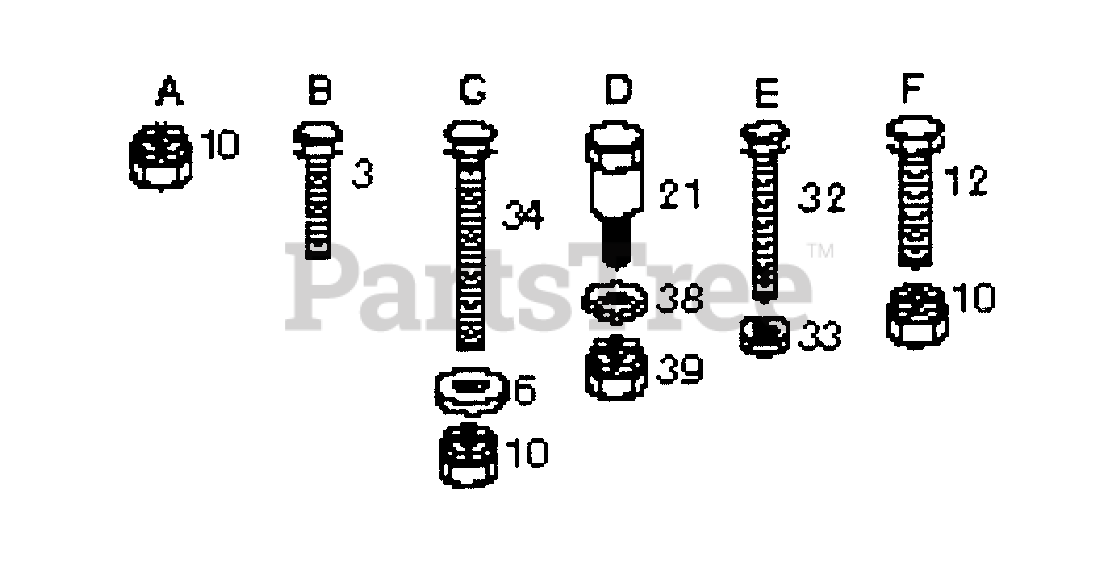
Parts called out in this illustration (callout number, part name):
3	Screw, Tap. Hex Hd. #10 - 24 x 1/2
6	Washer 13/32 x 13/16 x 12 Ga.
10	Nut, Crownlock 3/8 - 16
12	Bolt, Hex 3/8 - 16 x 3/4
21	Bolt, Shoulder 3/8 - 16
32	Bolt, Hex 5/16 - 18 x. 3/4
33	Locknut 5/16 - 18
34	Bolt, Hex 3/8 - 16 x 1
38	Washer, Spring
39	Locknut, Flange 3/8
